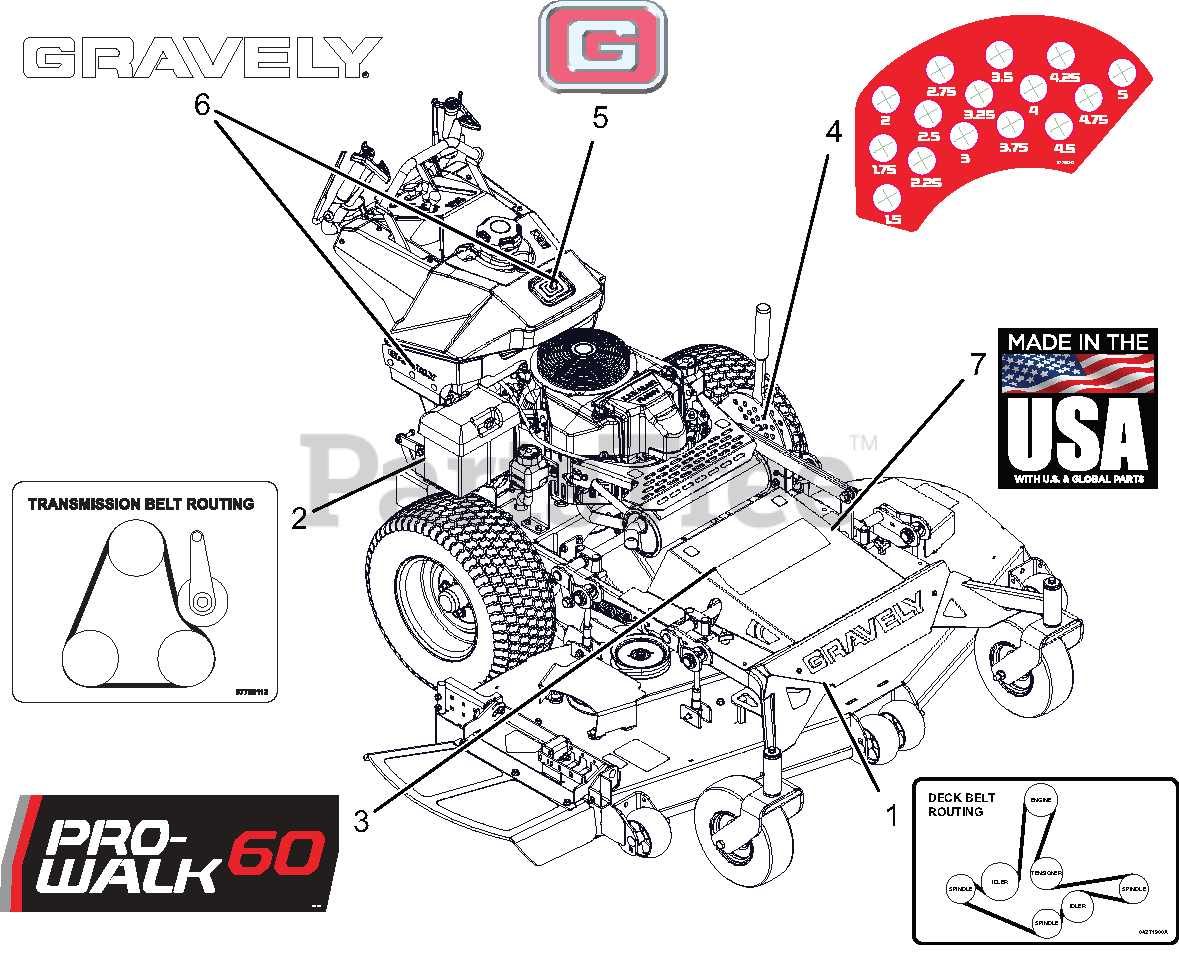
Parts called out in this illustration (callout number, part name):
1	DECAL, BELT ROUTING
2	DECAL, HYDRO BELT 36 PROSTANCE
3	DECAL, PRO WALK 60"
4	DECAL, HOC
5	DECAL, GRAVELY BRAND
6	DECAL, 6.5" GRAVELY LOGO
7	DECAL, MADE IN USA
